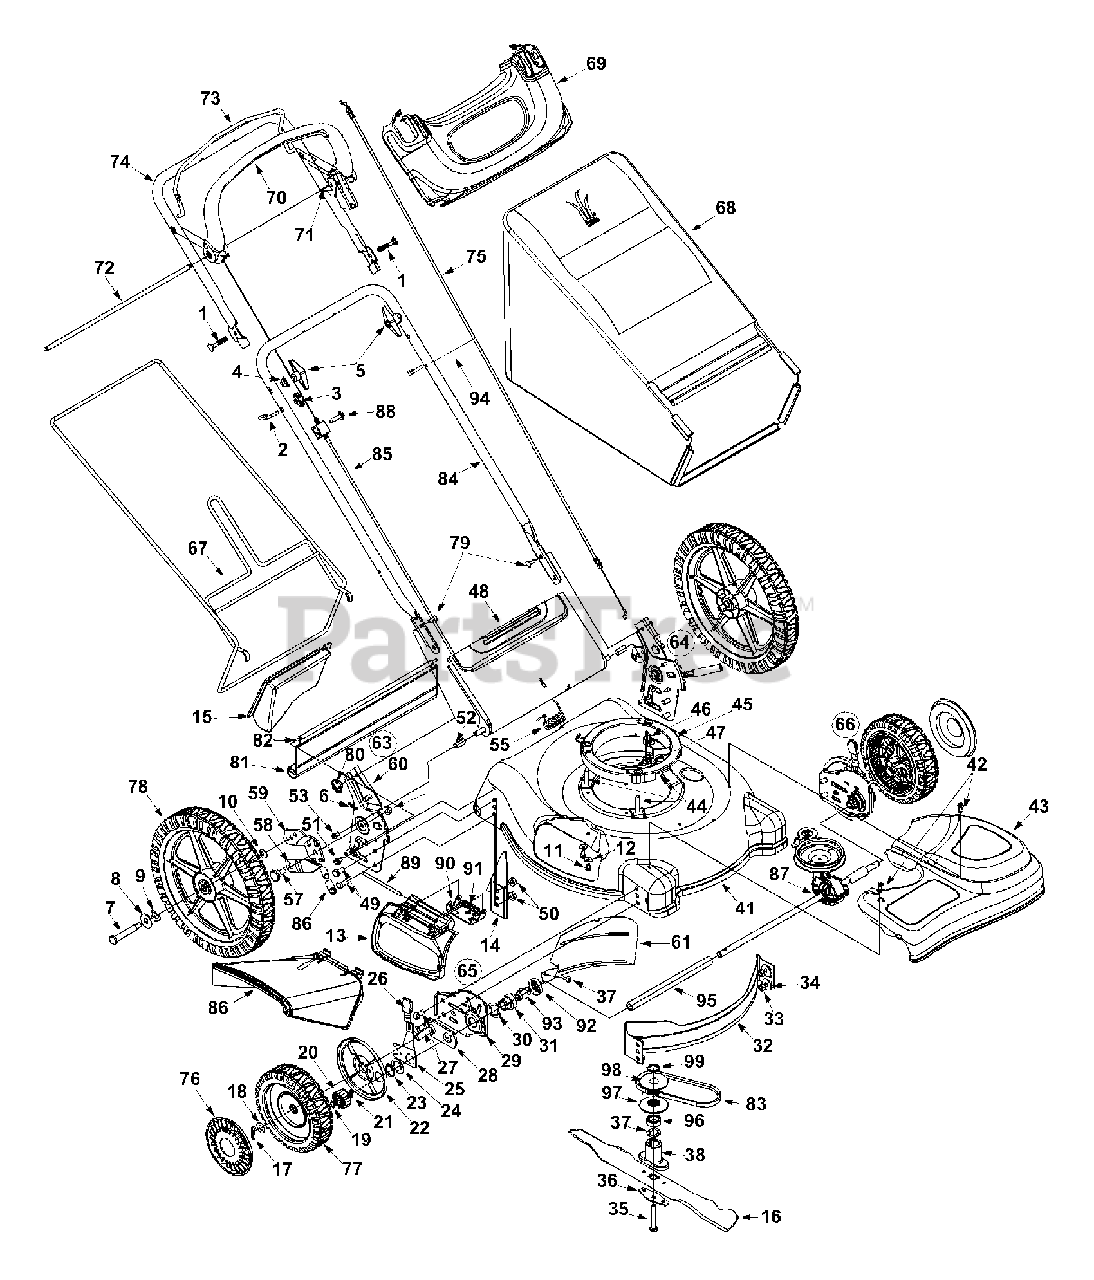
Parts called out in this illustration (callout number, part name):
1	Carriage Bolt
2	Rope Guide
3	Wing Nut
4	Saddle Washer
5	Handle Knob
6	Hairpin Clip
7	Shoulder Screw
8	Flat Washer .510 I.D. x 1.373 O.D.
9	Spring Wash. .500 I.D. x 1.00 O.D.
10	Bell Washer .375 I.D. x .870 O.D.
11	Tapp Screw 1/4-20 x .500
12	Bell Wash. .265 I.D. x .75 O.D.
13	Mulching Plug (Hinged)
15	Mulching Plug
16	Mulching Blade w/Star
17	Hairpin Clip
18	Flat Washer
19	Snap Ring
20	Gear 14T RH
21	Dowel Pin
22	Wheel Dust Cap
23	Snap Ring
24	Washer DD 1.5" O.D.
25	Front Lever RH
26	Knob
27	Hex Screw
28	Pivot Plate Assembly
30	Wave Washer
31	Bearing Support
34	Bell Washer
35	Hex Bolt
36	Blade Bell Support
37	Wave Washer
38	Blade Adapter
43	Transmission Cover
44	TT Screw
45	Engine Spacer Assembly
46	Belt Keeper Pin
47	Hex Nut 1/4-20
50	Flange L-Nut 3/8-16
51	AB Tap Screw 1/4-14 x .625"
52	Spacer
53	Pan Hd. Screw 1/4-20 x .5"
55	Torsion Spring
57	Shoulder Screw
58	Spring Lever
59	Pivot Bar LH
60	Handle Bracket Assembly RH
65	Height Adjuster Ass'y Comp. RH
66	Height Adjuster Ass'y Comp. LH
68	Grass Bag w/Half Sail
69	Handle Panel
70	Drive Handle
71	Bail Stop
72	Control Rod
73	Bail Handle
75	Control Cable
76	Hub Cap
77	Wheel 8 x 2
78	Wheel 14 x 2
79	Carriage Bolt
80	Wing Nut
81	Trail Shield
82	Wire
83	V-Belt
85	Drive Cable
86	Chute Deflector
87	Transmission Assembly Comp.
88	TT-Scr. 5/16-18
89	Hinge Pin
91	Torsion Spring
92	Bearing Retainer
93	Bearing Sleeve .50 I.D.
94	Cable Tie
95	Sleeve Spacer LH
96	Sleve Spacer .88 I.D. x 1.190 O.D.
97	Half Pulley
98	Half Pulley
99	Sleve Spacer .88 I.D. x 1.130 O.D.
